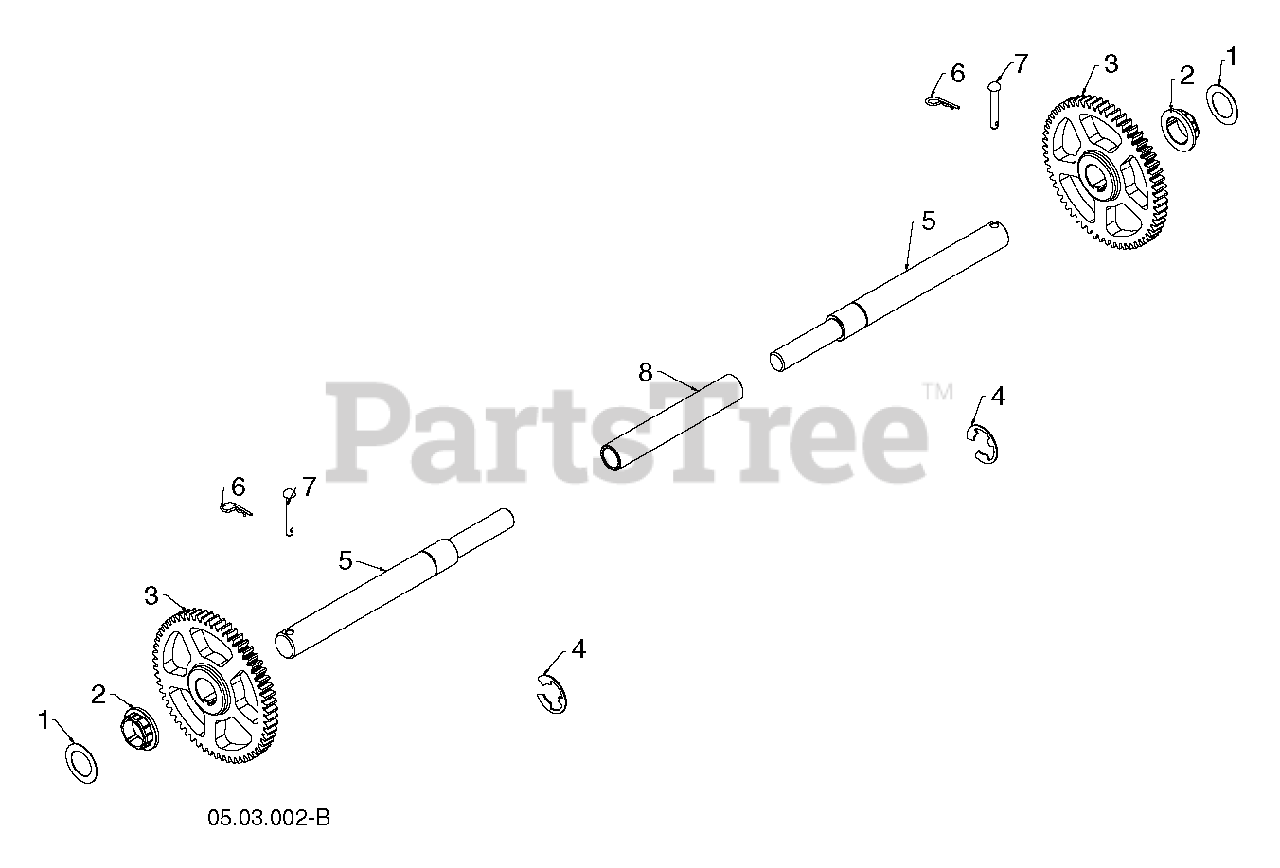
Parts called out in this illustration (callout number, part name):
1	WASHER 1.00
2	Hex Shaft Bushing
4	E RING HYT
5	AXLE AXLE, SPLIT SHAFT Ã 1.00
6	RETAINER M
7	RIVET
8	SLEEVE SLEEVE, AXLE SLEEVE
